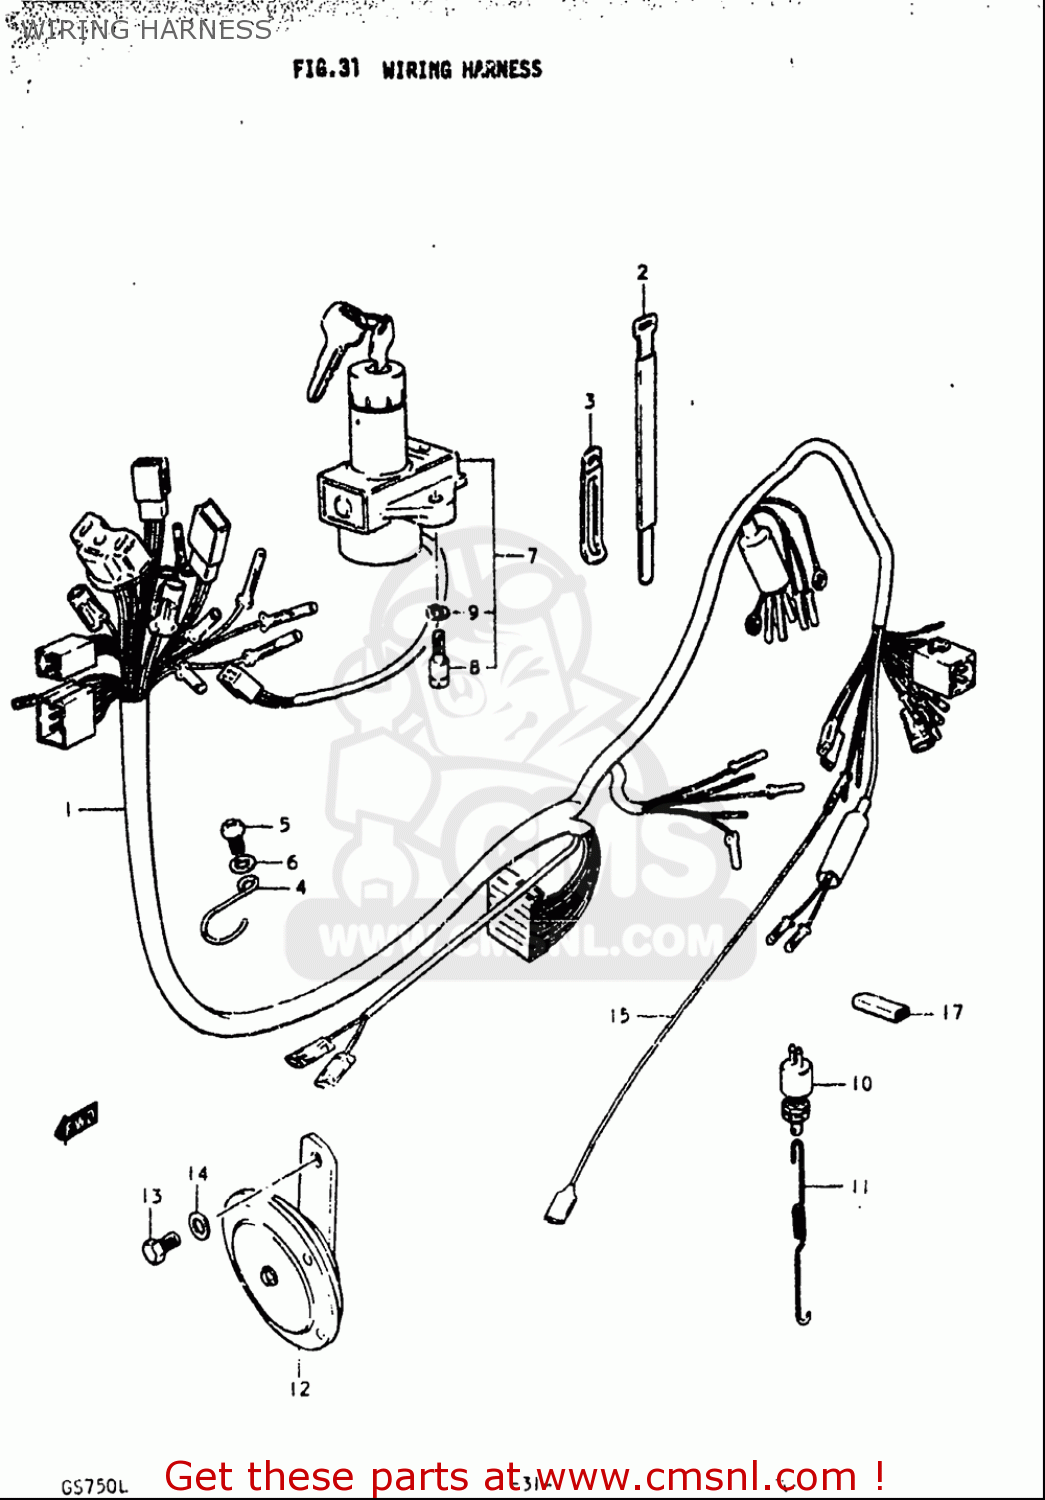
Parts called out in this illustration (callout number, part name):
2	CLAMP
3	CLAMP(L:80 T:1.0)
4	CLIP,WIRING HARNESS
5	SCREW
6	WASHER
7	SWITCH ASSY,IGNITION
8	BOLT
9	WASHER,LOCK
10	SWITCH ASSY,BRAKE LAMP
11	SPRING
12	HORN ASSY
13	BOLT
14	WASHER
15	WIRE,OIL PRESSURE SWITCH LEAD
16	PROTECTOR,WIRING HARNESS
